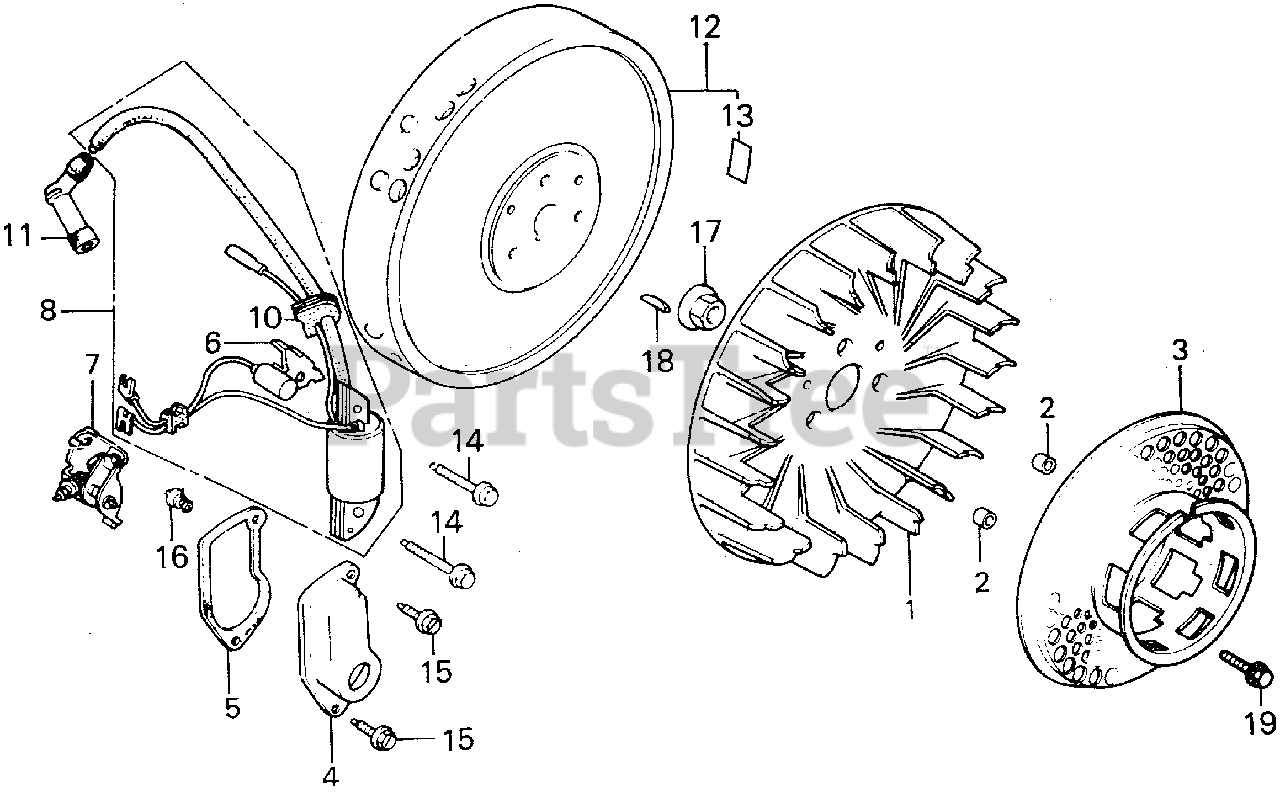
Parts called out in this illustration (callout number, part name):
1	FAN, COOLING
2	COLLAR, FAN
3	PULLEY, STARTER
4	COVER, POINTS
5	GASKET, POINT COVER
6	CONDENSER
7	POINTS ASSY.
8	COIL ASSY., IGNITION
10	GROMMET, WIRE
11	CAP ASSY., NOISE SUPPRESSOR
14	BOLT, FLANGE (6X32)
15	BOLT, FLANGE (5X10)
16	SCREW-WASHER (5X12)
17	NUT, SPECIAL (14MM)
18	KEY, SPECIAL WOODRUFF (25X18)
19	BOLT, FLANGE (6X16)
